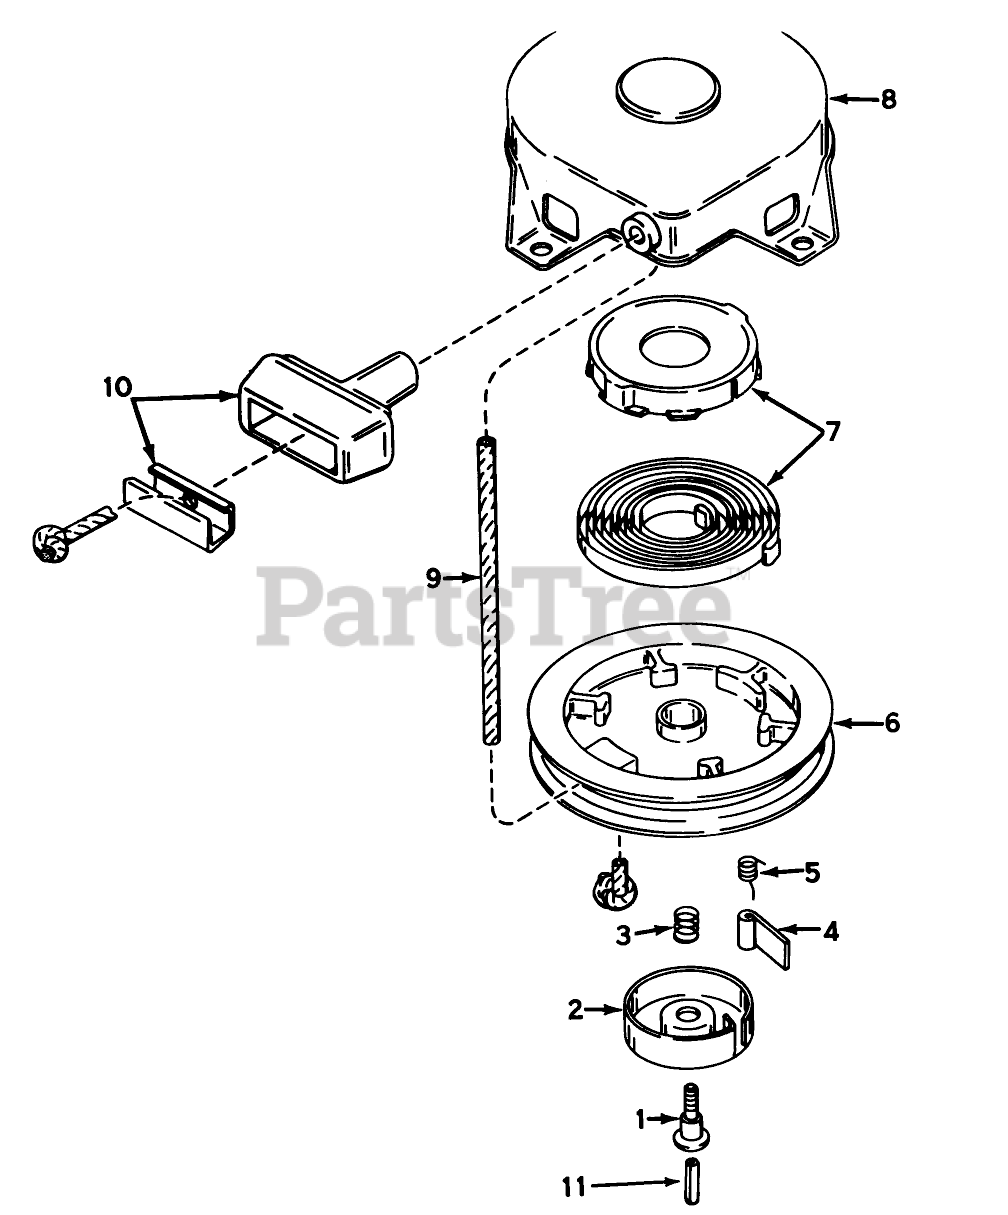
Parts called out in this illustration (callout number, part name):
1	Screw
2	Retainer
3	Spring-Brake
4	Dog-Starter
5	Spring-Dog
7	Spring & Keeper Assy
8	STARTER HOUSING ASSY
9	Rope Starter
10	Assy., Starter
11	Centering
